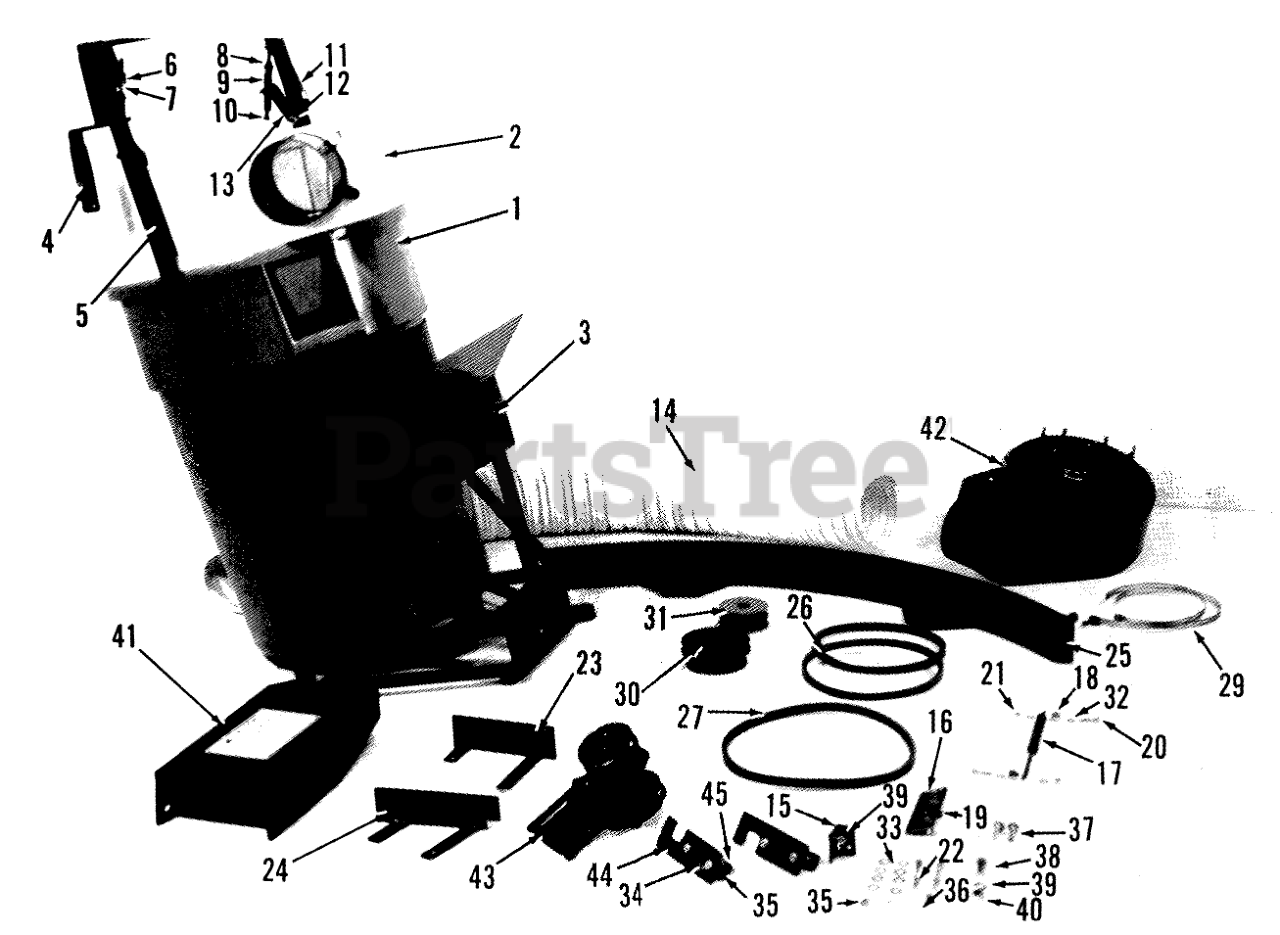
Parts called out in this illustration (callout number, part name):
1	Collector
3	Collector Frame
4	Grip
5	ASS'Y-CHANNEL SLIDE
6	TRUNNION-LIFT
7	HAIRPIN
8	Flanged Nut
9	Compression Spring
10	Bolt 5/16-18 x 6-3/4
11	Extension Spring
12	HAIRPIN
13	BRKT-L WELDMENT L.H.
14	HOSE-DISCHARGE 73"
15	Mower Bracket
16	Fender Bracket
17	GAS SPRING
18	SPACER
19	Bolt
20	Bolt
21	Nut
22	Bolt
23	Discharge Deflector 60" Mower
24	Discharge Deflector 50" Mower
25	Anti-Blowout Baffle
26	BELT-BLOWER DRIVE
27	Drive Belt (40.8")
29	Hose Clamps
30	PULLEY-CENTER
31	PULLEY-CENTER
33	Washer
34	Bolt
35	NUT
36	Bolt
37	Bolt
38	Bolt
39	Lockwasher
40	Eslok Nut
41	Belt Cover
42	Blower-Complete
43	Blower Dbl. Pulley Drive-Complete
44	Collector Mounting Bracket
45	BRACKET-BACK UP
